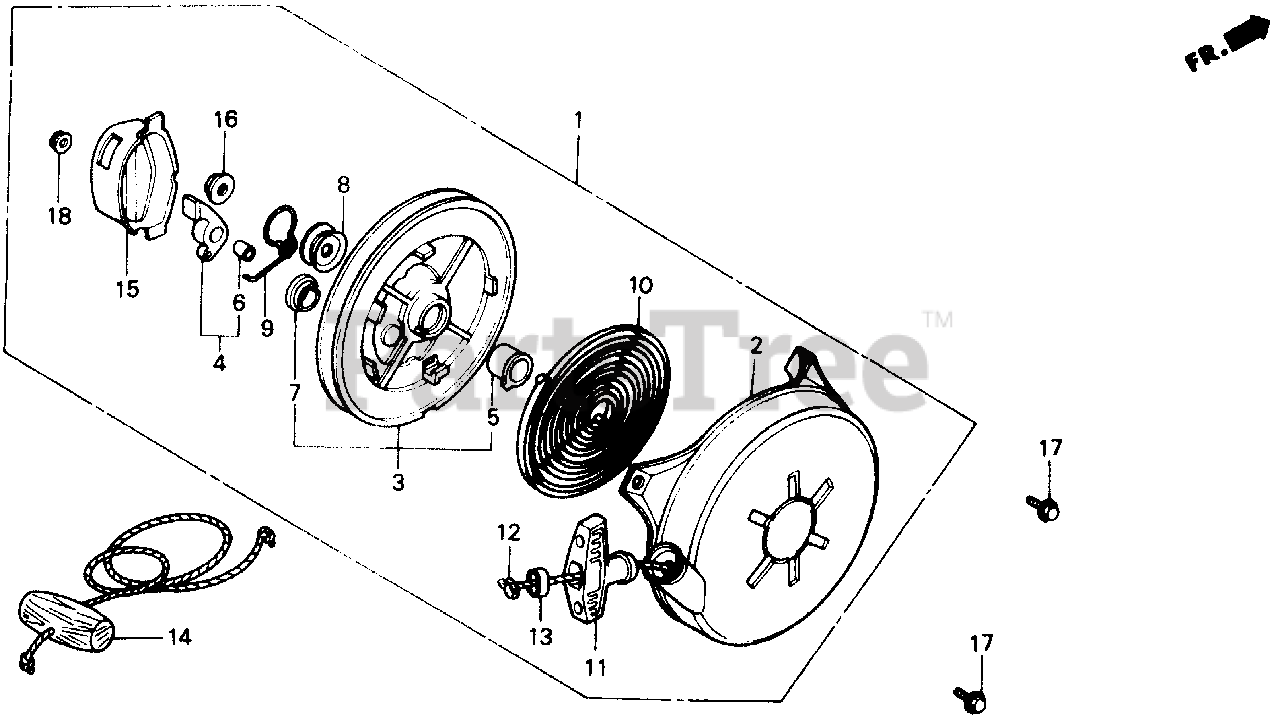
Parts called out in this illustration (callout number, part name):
1	STARTER ASSY., RECOIL (NOT AVAILABLE)
2	CASE, STARTER
3	REEL, STARTER
5	BOSS, REEL
6	BUSH, RATCHET
7	BUSH, REEL STARTER
8	PLATE, FRICTION
9	SPRING, FRICTION
10	SPRING, RETURN
11	GRIP, STARTER
12	ROPE, STARTER (#5X59")
13	SUPPORT, GRIP
14	ROPE, STARTER (#5X55") Use from Engine SN 1453515.
15	COVER, REEL STARTER
16	NUT, SELF-LOCK (8MM)
17	BOLT-WASHER (6X10)
17	BOLT, FLANGE (6X8)
18	NUT, FLANGE (5MM)
